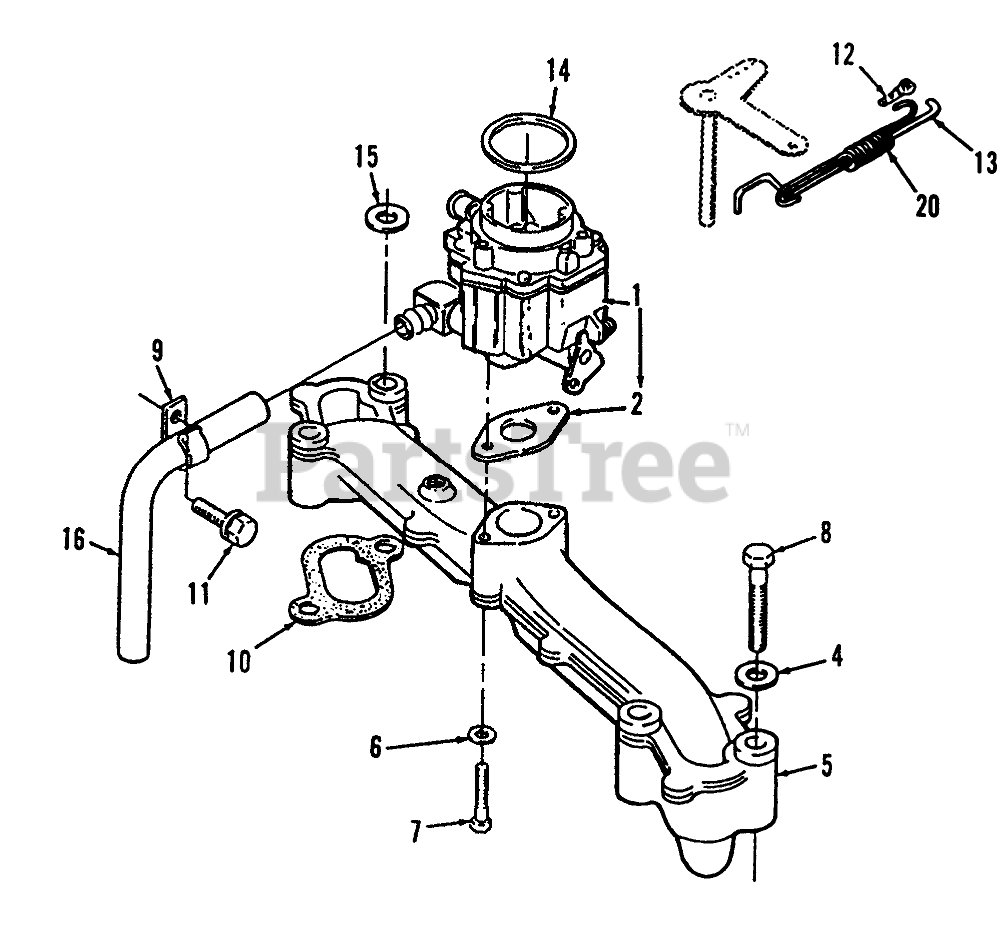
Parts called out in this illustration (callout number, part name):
1	Carburetor (Incl.Mounting Gasket,Elbow,&"O"Ring)
2	Gasket
4	WASHER-FLAT
5	MANIFOLD
6	Bolt
7	Bolt
9	Clip
10	GASKET
11	Screw
13	GOVERNOR CONTROL ROD
15	FLAT WASHER
16	FIXED-JET
20	Spring-Governor Rod
